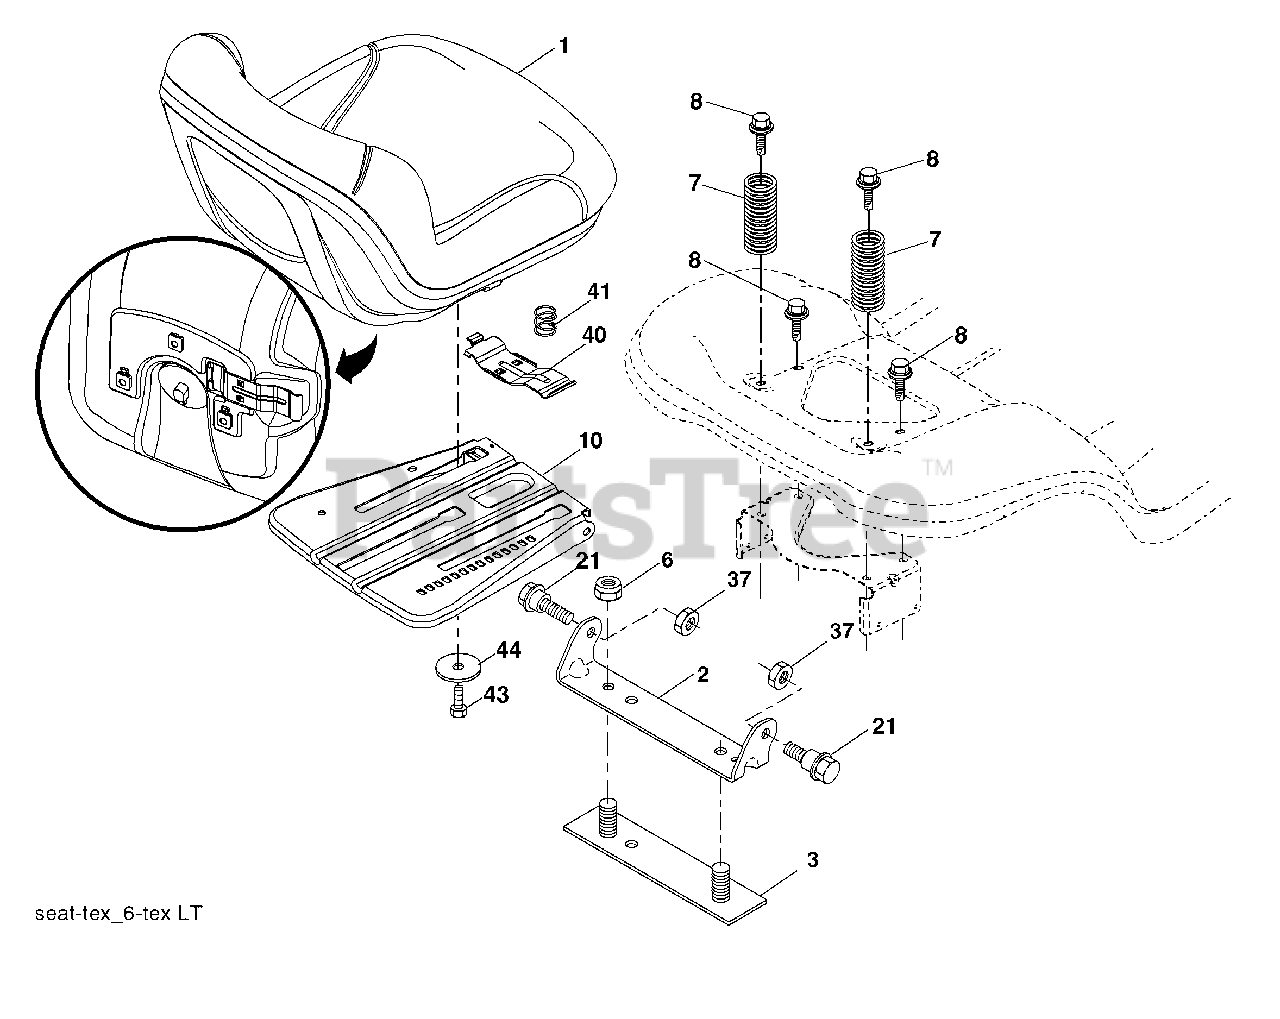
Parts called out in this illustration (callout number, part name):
1	Seat
2	Bracket Pivot Fender
3	Strap, Asm Fender
6	Nut, Lock w/Ins. 3/8-16 unc
7	Spring, Seat Cprsn
8	Bolt 5/16-18 unc x 3/4 w/Sems
10	Pan, Seat
21	Bolt, Shoulder 5/16-18
37	Nut, Lock 5/16-18 unc
40	Handle Slide Seat
41	Spring Latch Seat
43	Bolt Fin Hex 3/8-16 unc x 3/4
44	Washer 13/32 x 2-3/8 x 12 Ga.
